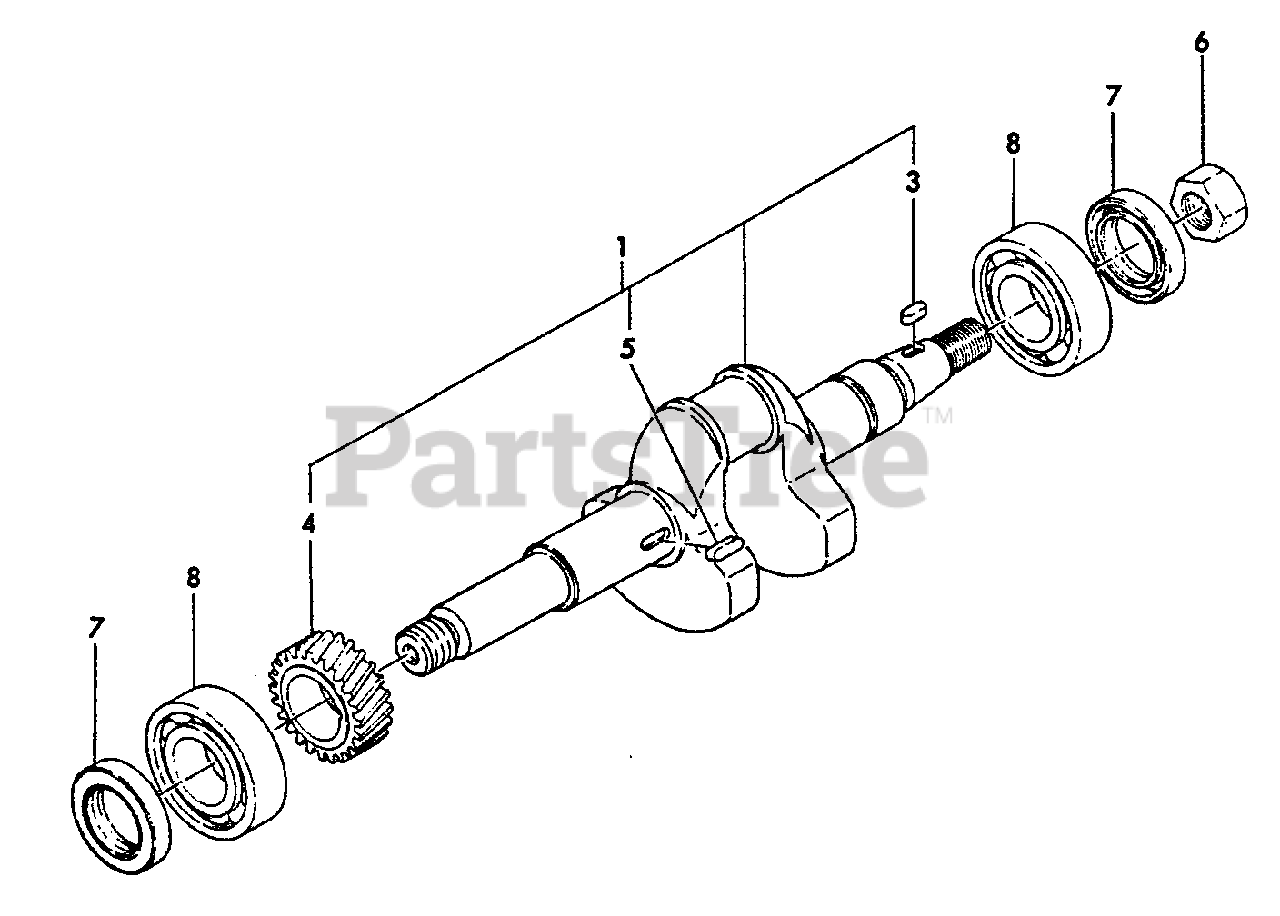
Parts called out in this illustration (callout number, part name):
1	CRANKSHAFT ASSY
3	KEY - 4X10
4	GEAR, CRANKSHAFT
5	KEY - 4X12
6	NUT - 14
7	SEAL, OIL
8	BEARING, BALL - 6205C3
